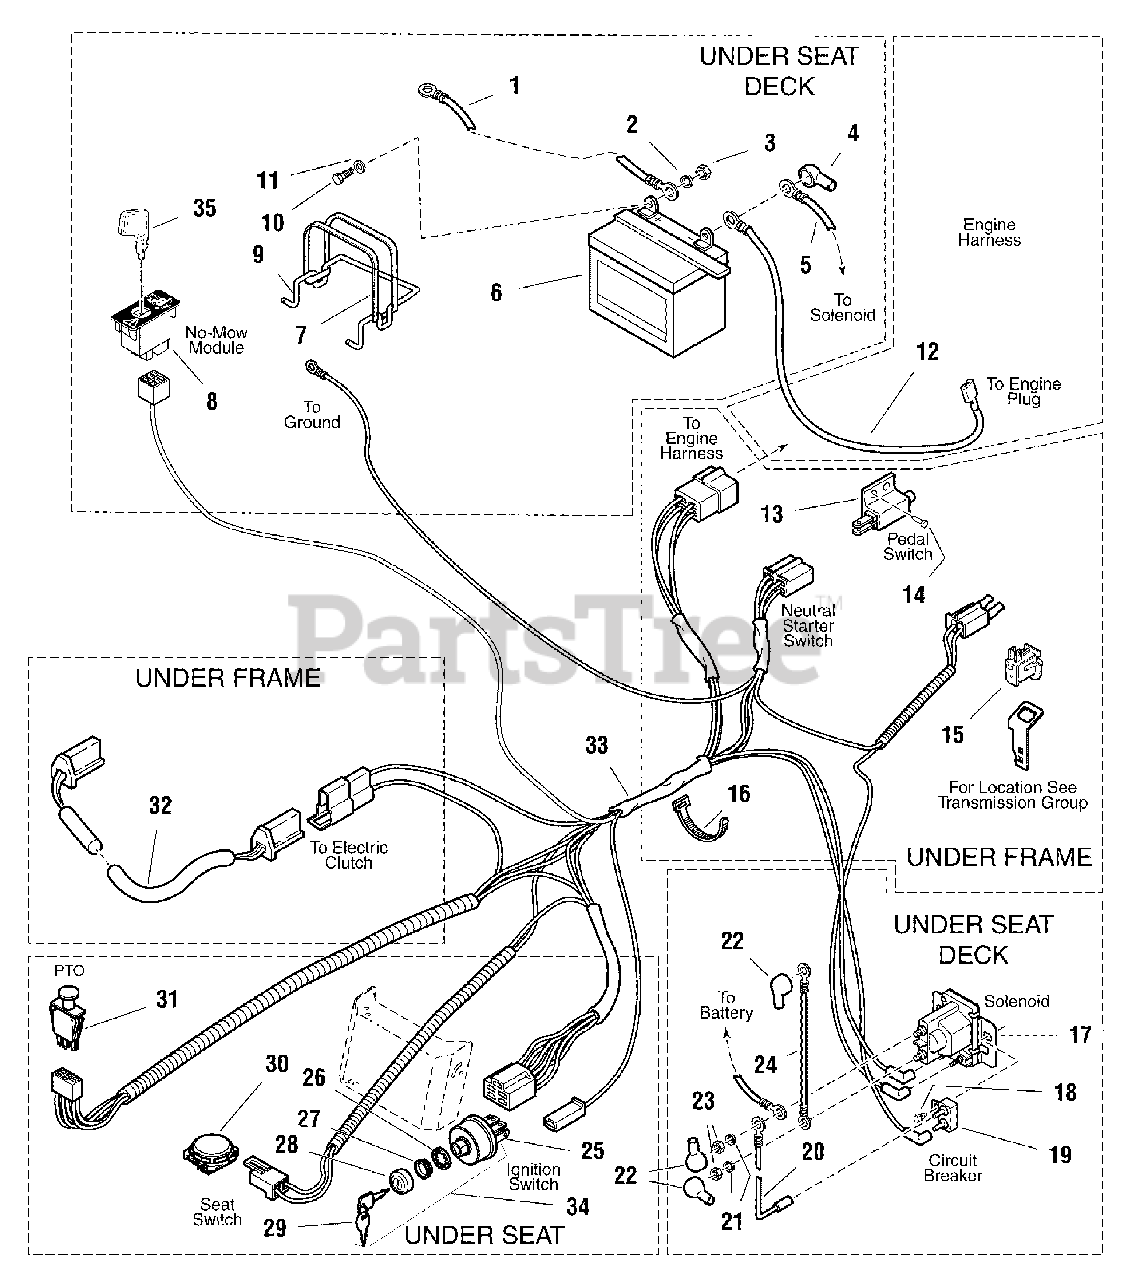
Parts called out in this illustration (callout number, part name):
1	CABLE, Battery to Ground
2	WASHER, Lock, 1/4
3	NUT, Hex 1/4-20
4	BOOT, Insulator
5	CABLE, Battery to Solenoid
7	STRAP, Battery
8	SWITCH, RMO Module Only
9	BRACE, Battery
10	CAPSCREW, Hex Head, 1/4-20 x 3/4
11	WASHER
12	WIRE ASSEMBLY, 16GA
13	SWITCH, Neutral Start
15	SWITCH, Push Button (N.O.) (RMO Models Only)
16	TIE, Self-Locking
17	SOLENOID
18	CAPSCREW, Hex Head, Taptite, 1/4-20 x 1/2
19	CIRCUIT BREAKER
20	WIRE ASSEMBLY
21	LOCKWASHER, 5/16
22	COVER, Terminal
23	NUT, Hex, 5/16-24
24	CABLE, Solenoid to Starter
25	SWITCH, Ignition (6 pole)
26	WASHER, Internal Tooth, 5/8
27	NUT
28	COVER, Keyswitch
29	KEYS (Set of 2 Keys)
30	SWITCH, Seat, Gray Switch, Gray Retainer
31	SWITCH, Seat, Gray Switch, Black Retainer
31	* SWITCH, PTO, Electric Clutch
32	WIRE HARNESS, Clutch (RMO Models Only)
32	WIRE HARNESS, Clutch
33	HARNESS, Wiring (RMO Models Only)
33	HARNESS, Wiring
34	IGNITION KEY SWITCH ASSEMBLY
35	KEY, RMO Module, Plastic
